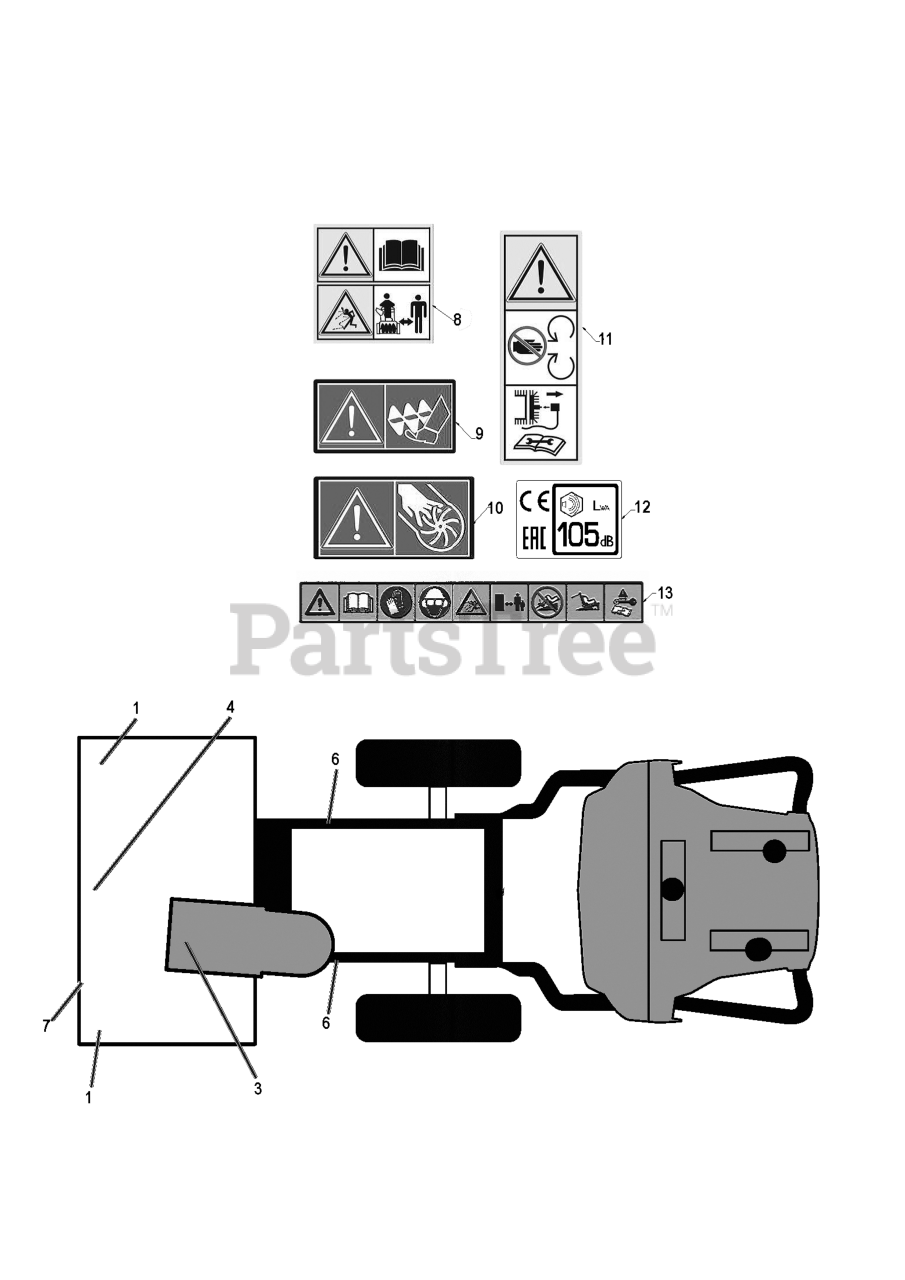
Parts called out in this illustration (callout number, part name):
1	DECAL.AUGER.SAFETY.
3	DECAL.CHUTE.SAFETY.EU/SC.17
4	DECAL.AUGER."
6	DECAL.BELT.GUARD.
7	DECAL SNOW BUCKET TRIM GRAPHIC
8	DECAL.AUGER."
9	DECAL.CHUTE.SAFETY.EU/SC.17
10	DECAL.AUGER.SAFETY.
11	DECAL.BELT.GUARD.
12	DECAL.NOISE.LEV.105/CE.EAC.UKR
